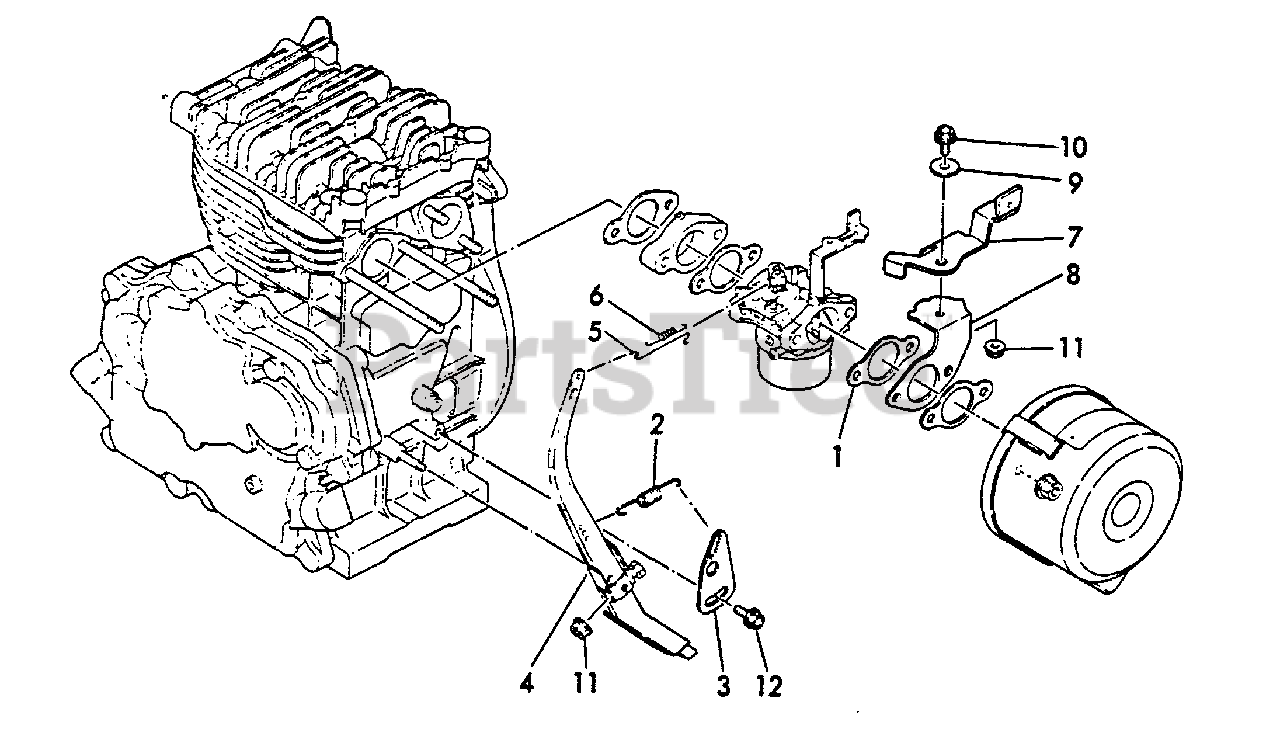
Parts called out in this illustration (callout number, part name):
1	GASKET, INTAKE
2	SPRING, REGULATOR
3	HANDLE, REGULATOR
4	LEVER, GOVERNOR
5	LINK, THROTTLE
6	SPRING
7	LEVEL ASSY
8	BRACKET, LEVER
9	COLLAR
10	BOLT - 6X12 -- PLATED
11	NUT - 6 -- FLANGE
12	BOLT - 6X8 -- PLATED
